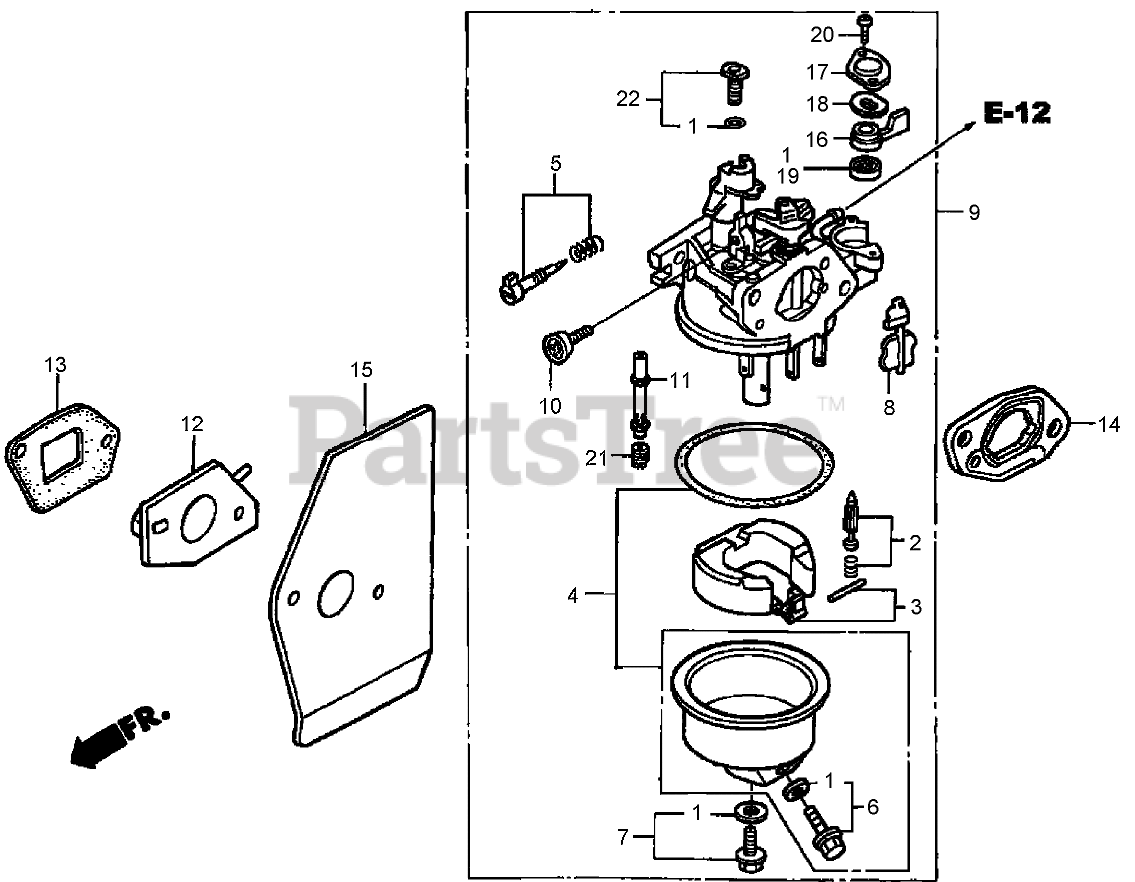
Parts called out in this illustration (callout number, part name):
1	Gasket Set
2	FLOAT VALVE SET
3	Float Set
4	FLOAT CHAMBER SET
5	PILOT SCREW SET
6	DRAIN SCREW SET
7	SCREW SET
8	Choke Set
9	CARBURETOR ASM
10	SCREW- STOP, THROTTLE
11	Nozzle-Main
12	Insulator-Carburetor
13	Gasket-Insulator
14	Spacer-Carburetor
15	Gasket-Carburetor
16	LEVER-PETCOCK
17	PLATE-SETTING, LEVER
18	SPRING-LEVER, PETCOCK
19	GASKET-PETCOCK
20	SCREW-PAN (3X6)
21	JET-MAIN (No. 60)
21	JET-MAIN (No. 62)
21	JET-MAIN (No. 65)
22	PILOT JET SET (No. 35)
